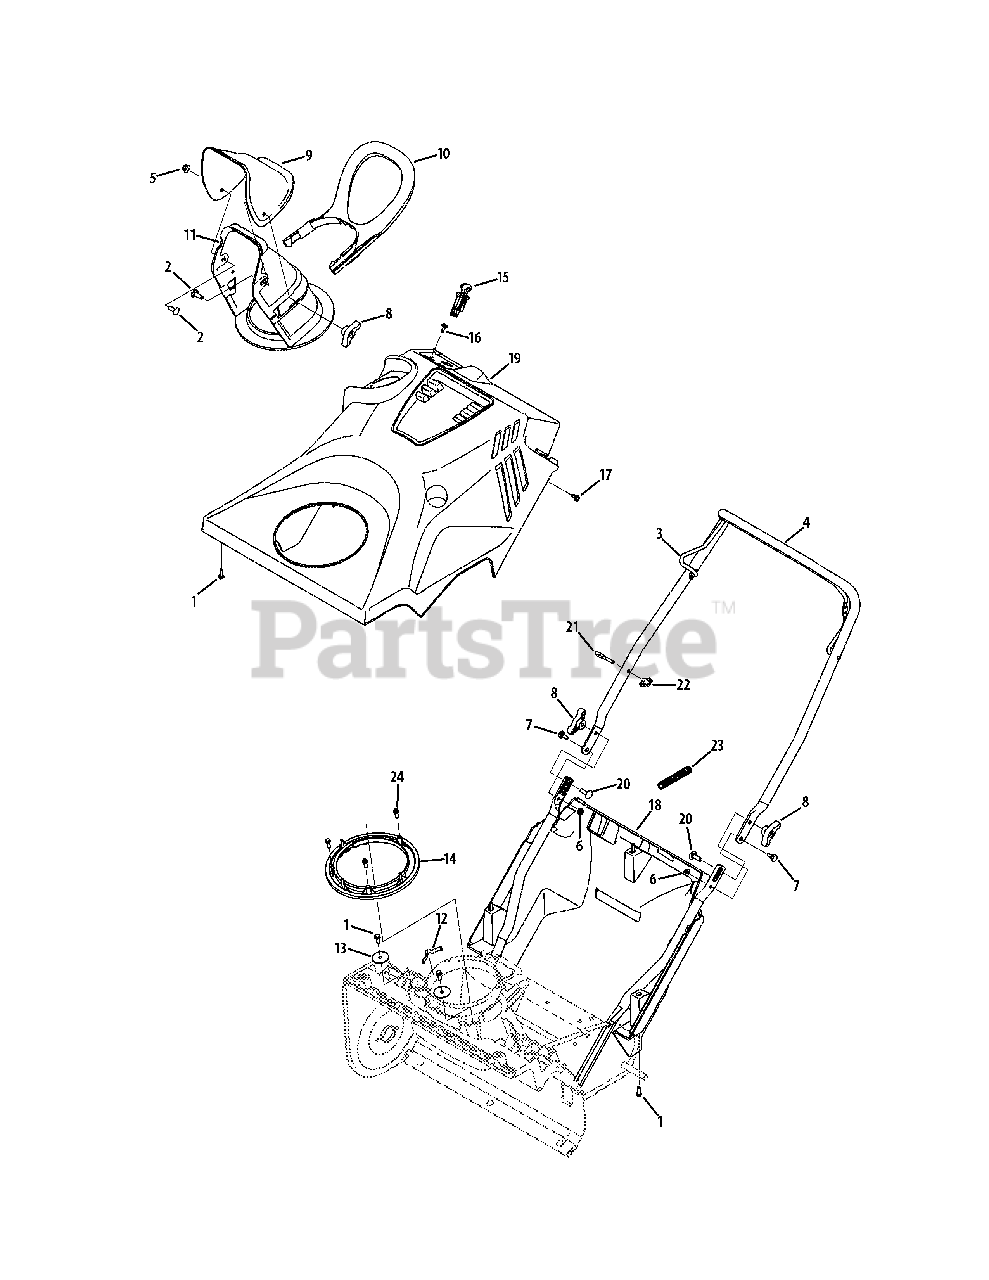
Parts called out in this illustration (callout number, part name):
1	Screw, 1/4-15 x 0.75
2	Carriage Bolt, 5/16-18 x .750
3	Auger Bail
4	Upper Handle
5	Flange Lock Nut, 5/16-18
6	Flange Lock Nut, 1/4-20
7	Shoulder Screw, 1/4-20 x .375 x .148
8	Wing Knob, 5/16-18
9	Upper Chute
10	Chute Handle
11	Lower Chute
12	Chute Adjustment Spring
13	Flat Washer, .28 x 1.51 x .066
14	Chute Ring
15	Ignition Switch Assembly
16	Hex Washer Screw, 1/4-15 x .50
17	Hex Washer Screw, 1/4-20 x .625
18	Bottom Cover
19	Top Cover
20	Carriage Screw, 5/16-18 x 1.00
21	Eye Bolt, 1/4-20
22	Handle Knob
23	Conduit
24	Hex Washer Screw, 1/4 x .750
